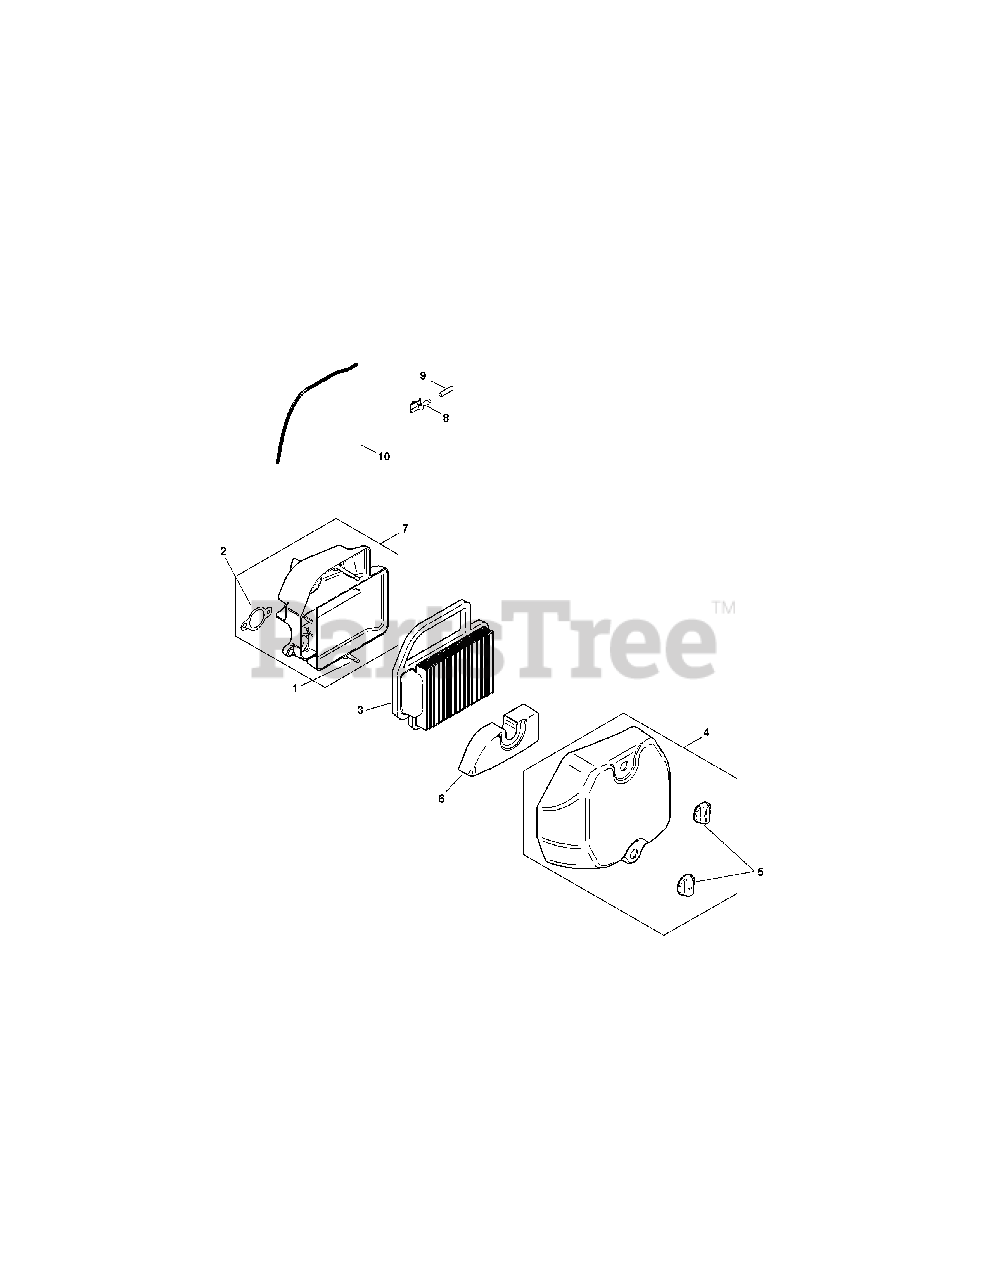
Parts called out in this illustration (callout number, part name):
1	Air Cleaner Base Stud
2	Air Cleaner Base Gasket
3	Air Cleaner Element/Filter
4	Air Cleaner Cover Kit
6	Pre-Cleaner Element (Dry)
7	Air Cleaner Base Kit
8	Evaporative Connector
10	Hose, Evaporative, 20"
